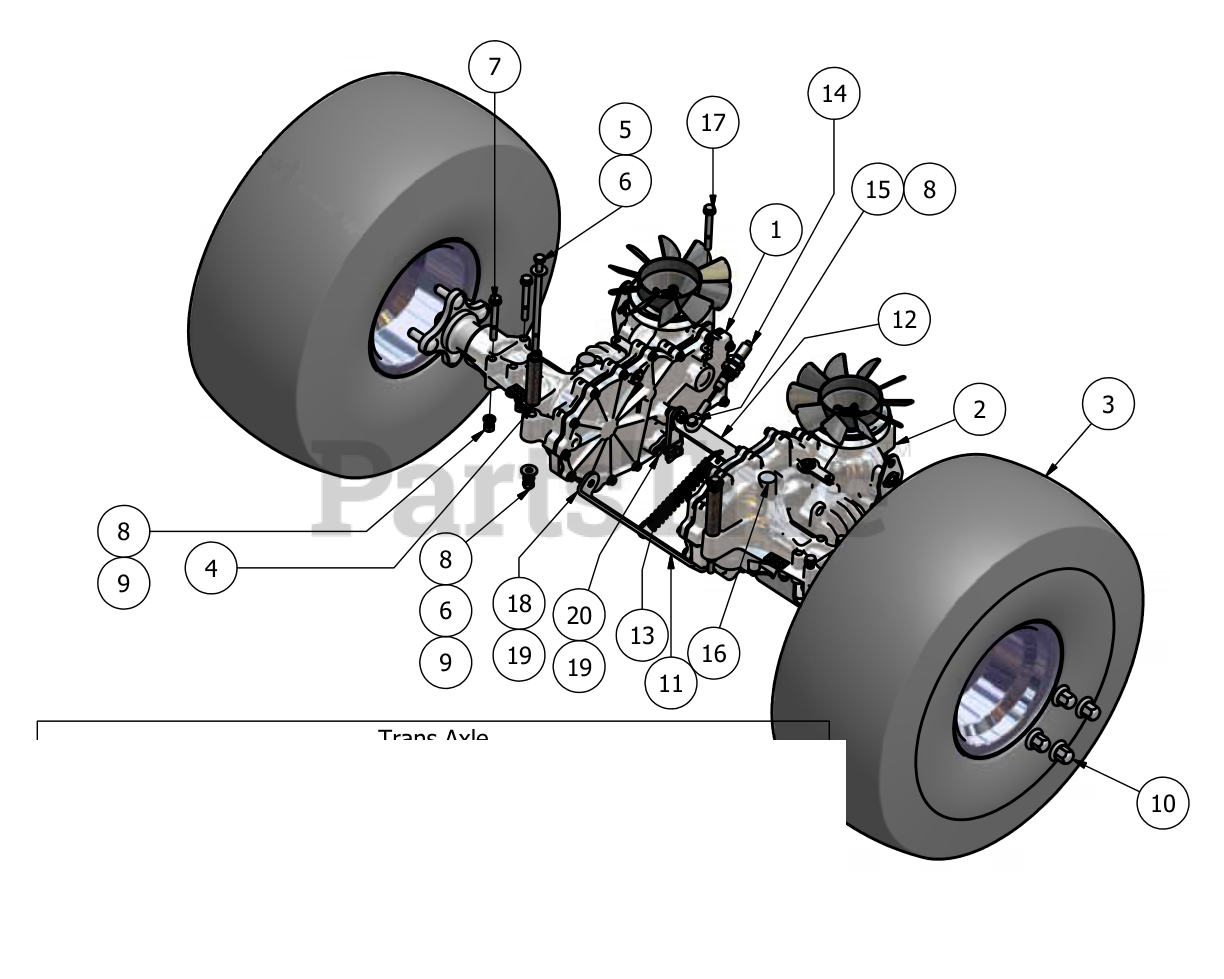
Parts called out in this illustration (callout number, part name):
1	Axle-Fan Left
2	Axle-Fan Right
3	Tire and Wheel Assembly
4	3 1/4" Transaxle Spacer
5	5/16"x 6" Hex Bolt
6	5/16 Lock Washer
7	5/16"x 3" Hex Bolt
8	5/16 Hex Nut
9	5/16" Flat Washer
10	1/2" Acorn Lug Nut
11	Crossover Brake Bracket
12	Crossover Bar
14	Brake Cable
15	5/16" x 3/4" Hex Bolt
16	45 Degree Fitting
17	5/16" x 2 1/2" Hex Bolt
18	3/8" x 2" Hex Bolt
19	3/8" Nylock Nut
20	3/8" x 1" Hex Bolt
21	1/2" Hex Nut
22	Transaxle Filter
